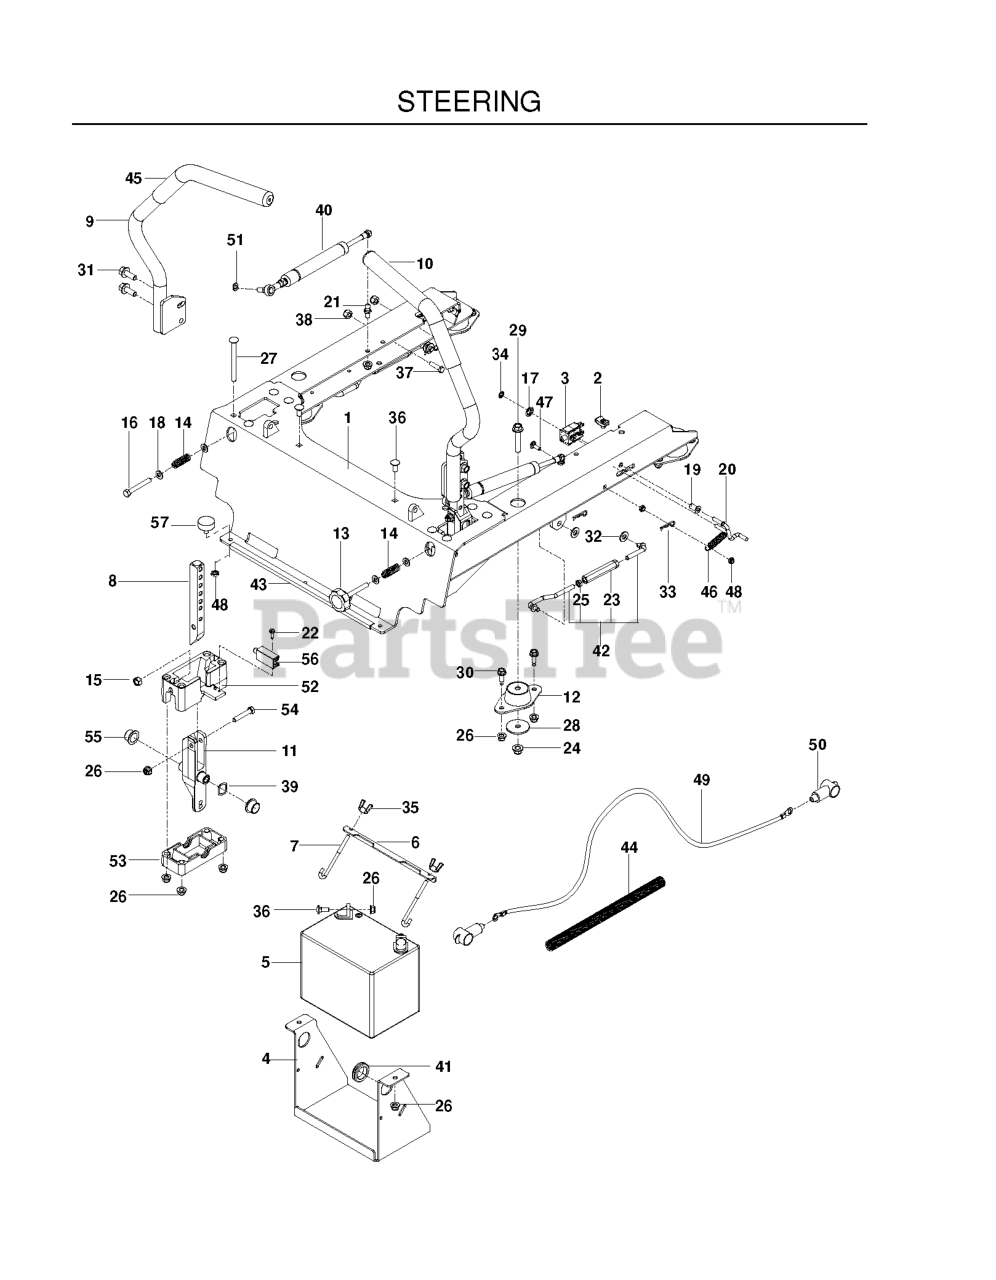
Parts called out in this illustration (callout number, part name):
1	FRAME.SEAT.MOUNT.ORANGE
2	U-CLIP 5/16-18 NUT RETAINER
3	SWITCH, BRAKE 3P
4	BRACKET, BATTERY, BLK
5	BATTERY, 12 V 330 AMP
6	BRACKET, BATTERY MOUNT
7	HOOK, "J"
8	LEVER, MOTION
9	LEVER, W/GRIP, RT
10	LEVER, W/GRIP, LT
11	LEVER, CONTROL
12	MOUNT, ISO
13	KNOB
15	NUT 5/16C HEX
16	HCS 5/16-18 X 2 1/2 TPBLT
17	NUT 3/8 PALNUT RTNG BLK PHOS
18	FLAT WASHER 5/16 SAE
19	BUSHING, 1/4 FLANGE
20	LINK, SWITCH
21	STUD.BALL.10MM
22	SCREW #10 X 1/2 SELF TAPPING
23	TURNBUCKLE, 3/8
24	NUT 3/8-16 HEX FLG NYLOC ZD
25	NUT 3/8-24 JAM
26	5/16-18 NYLOC FLANGE NUT
27	RHSNB 5/16-18 X 3-3/4 GR 5 ZD
28	WASHER, 3/8 SPEC
29	HHFS 3/8-16 X 2.0 GD 5
30	HHFS 5/16-18 X 3/4
31	HHFS 3/8-16 X 1 GRD 5 ZD
32	WASHER 3/8 SAE FLAT
33	HAIRPIN #2
34	NUT PUSH
35	WING NUT 1/4
36	BOLT 5/16C X 3/4" CARRIAGE
37	SCR #10-24 X .75 SKT HD BLK
38	NUT 10-24 NYLOC
39	WASHER, .825 X 1.087, WAVE
40	ASSEMBLY, DAMPENER
41	RUBBER GROMMET
42	ASSEMBLY, SEAT STRUT
43	RP.FLEX TRIM, BLK-LENGTH 1 FT
44	LOOM, SPLIT, CONVOLUTED
45	GRIP - DRIVE LEVER 12"
46	SPRING, EXTENSION
47	RHSNB 1/4C X 3/4
48	JAM NUT 1/4C (2 2 PW01)
49	CABLE, POSITIVE, 55"
51	WASHER.LOCK.HVY.HLCL.SPR.5/16
52	BLOCK, UPPER
53	BLOCK, LOWER
54	HCS 5/16C X 1 3/4
55	BEARING, FLANGE
56	SWITCH, INTERLOCK
57	BUMPER, 1/4-20 STUD, 1/4
